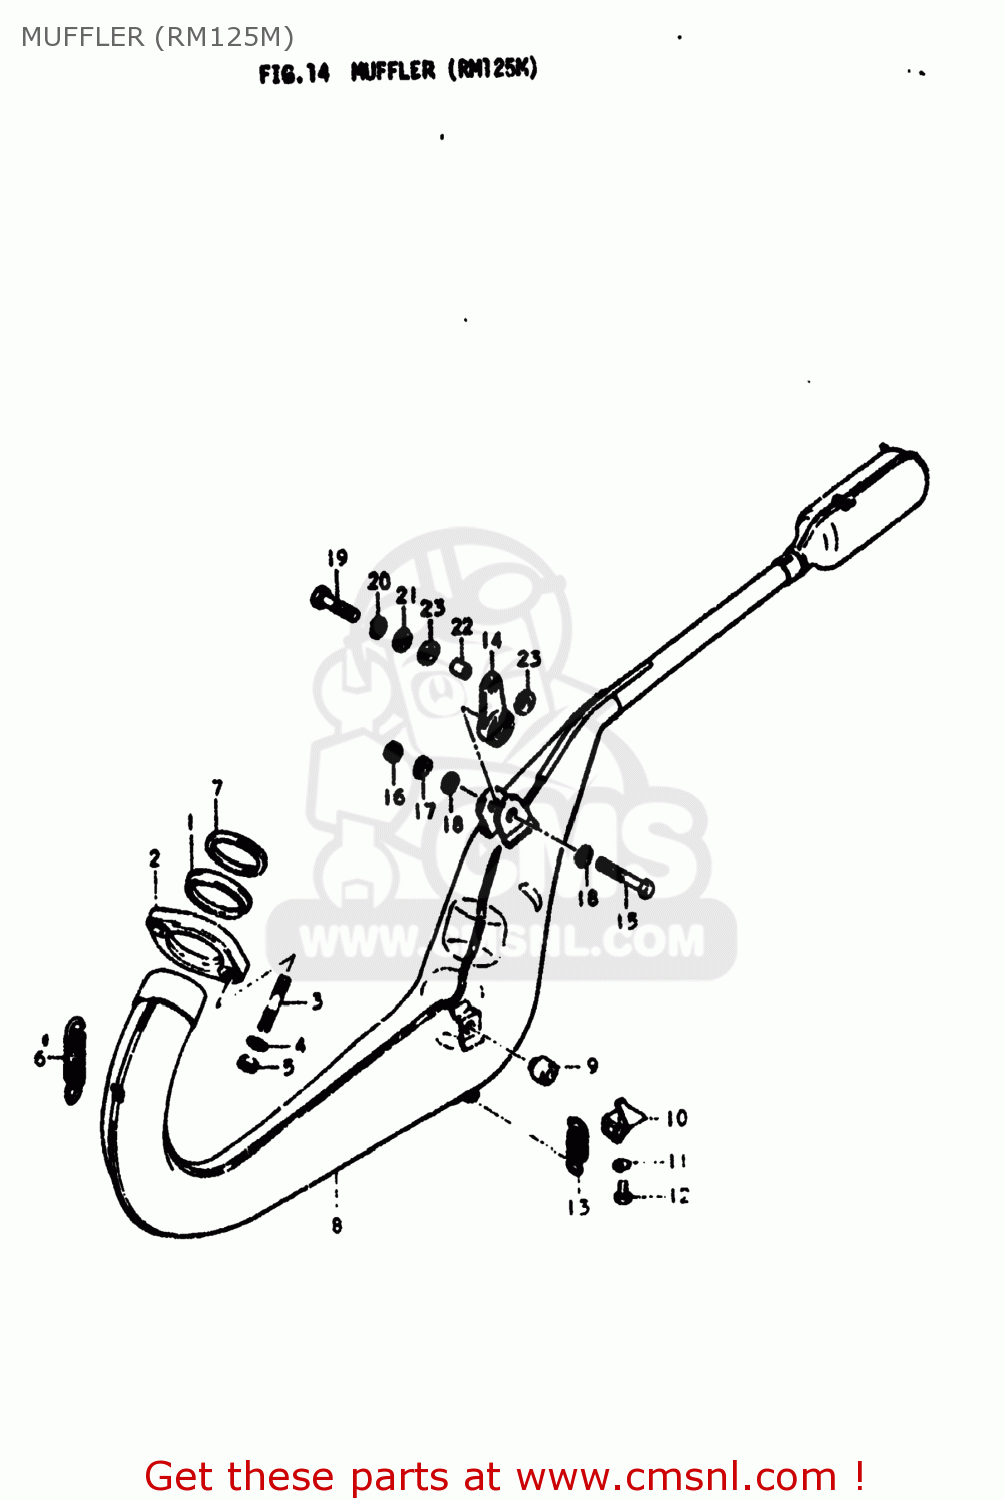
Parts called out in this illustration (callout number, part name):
1	GASKET,EXHAUST PIPE (NAS)
2	CLAMP,EXHAUST PIPE
3	STUD 6X20
4	LOCK WASHER
5	NUT
6	SPRING
7	CUSHION,EXHAUST PIPE
8	BODY,MUFFLER
9	CUSHION(11.5X22X20)
10	BRACKET, MUFFLER STOPPER
11	LOCK WASHER
12	BOLT
13	SPRING
14	DAMPER,MUFFLER SUPPORT
15	** SUPERSEEDED
16	NUT
17	LOCK WASHER
18	WASHER
19	BOLT
20	LOCK WASHER
21	WASHER
22	SPACER (8.6X13.8X9)
23	CUSHION
